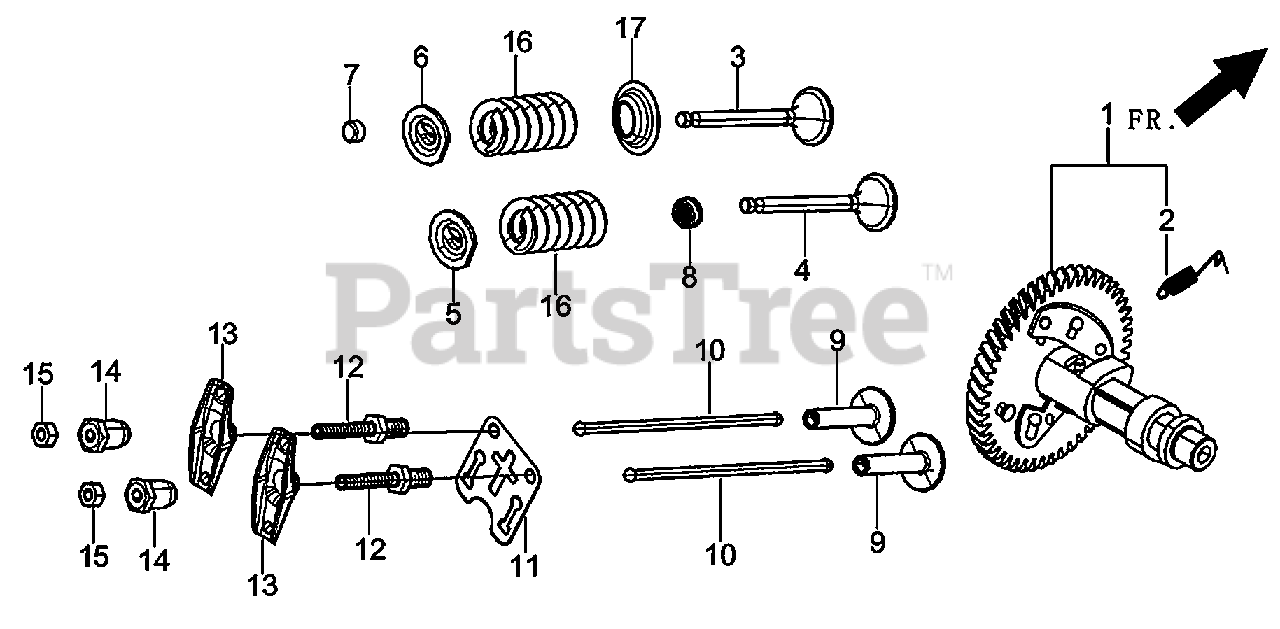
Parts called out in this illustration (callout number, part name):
1	CAMSHAFT ASSY.
3	VALVE, EXHAUST
4	VALVE, INTAKE
5	SEAT, VALVE SPRING
6	RETAINER EXHAUST VALVE
7	R0TATOR, VALVE
8	GUIDE, SEAL
9	TAPPET, VALVE
10	ROD, PUSH
11	PLATE, PUSH ROD GUIDE
12	BOLT, VALVE ADJUSTING
13	ROCKER, VALVE
14	NUT VALVE ADJUSTING
15	NUT, VALVE LOCK
16	SPRING, VALVE
17	RETAINER, VALVE SPRING
